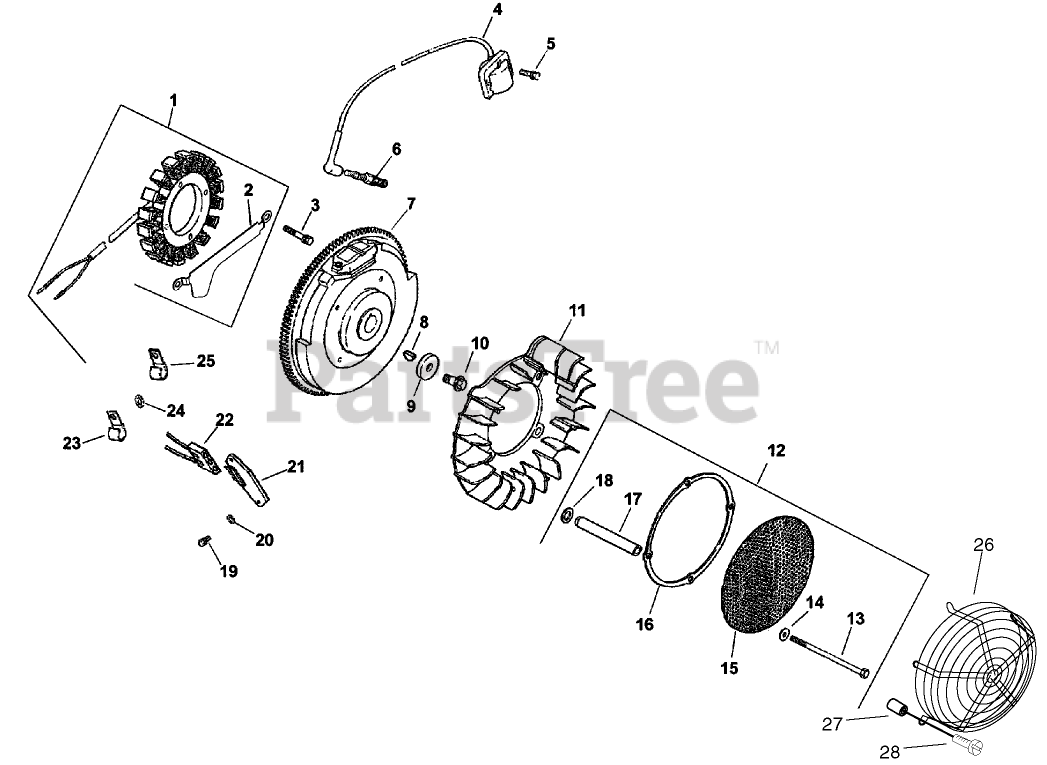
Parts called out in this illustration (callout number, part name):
1	Kit-Stator, 15 amp (Incl. Ref. # 2)
2	Bracket-Wire, Stator
3	SCREW-THREAD FORMING (M5X0.8X25)
4	Module-Ignition
5	SCREW-FLANGE, THREAD FORMING (M5X.8X20)
6	Spark Plug
7	Flywheel
8	KEY (3/16 X 5/8)
9	WASHER-FLAT (13/32)
10	SCREW-FLANGE (M10X1.5X45)
11	Fan
12	Kit-Screen, Chopper (Incl. Ref. #13-18)
13	Screw-HH (M6x1.0x100)
14	WASHER-FLAT (1/4)
15	Screen-Grass
16	Ring-Support
18	Washer-Spring (10MM)
19	SCREW-PHL HD (11-16X.88)
20	WASHER-FLAT (.188)
21	Rectifier-Regulator, 15 amp
22	Connector (3 contact)
23	CLIP-CABLE
24	WASHER-FLAT (1/4)
25	Clip-Cable
26	Guard-Wire
27	Spacer
28	Screw
